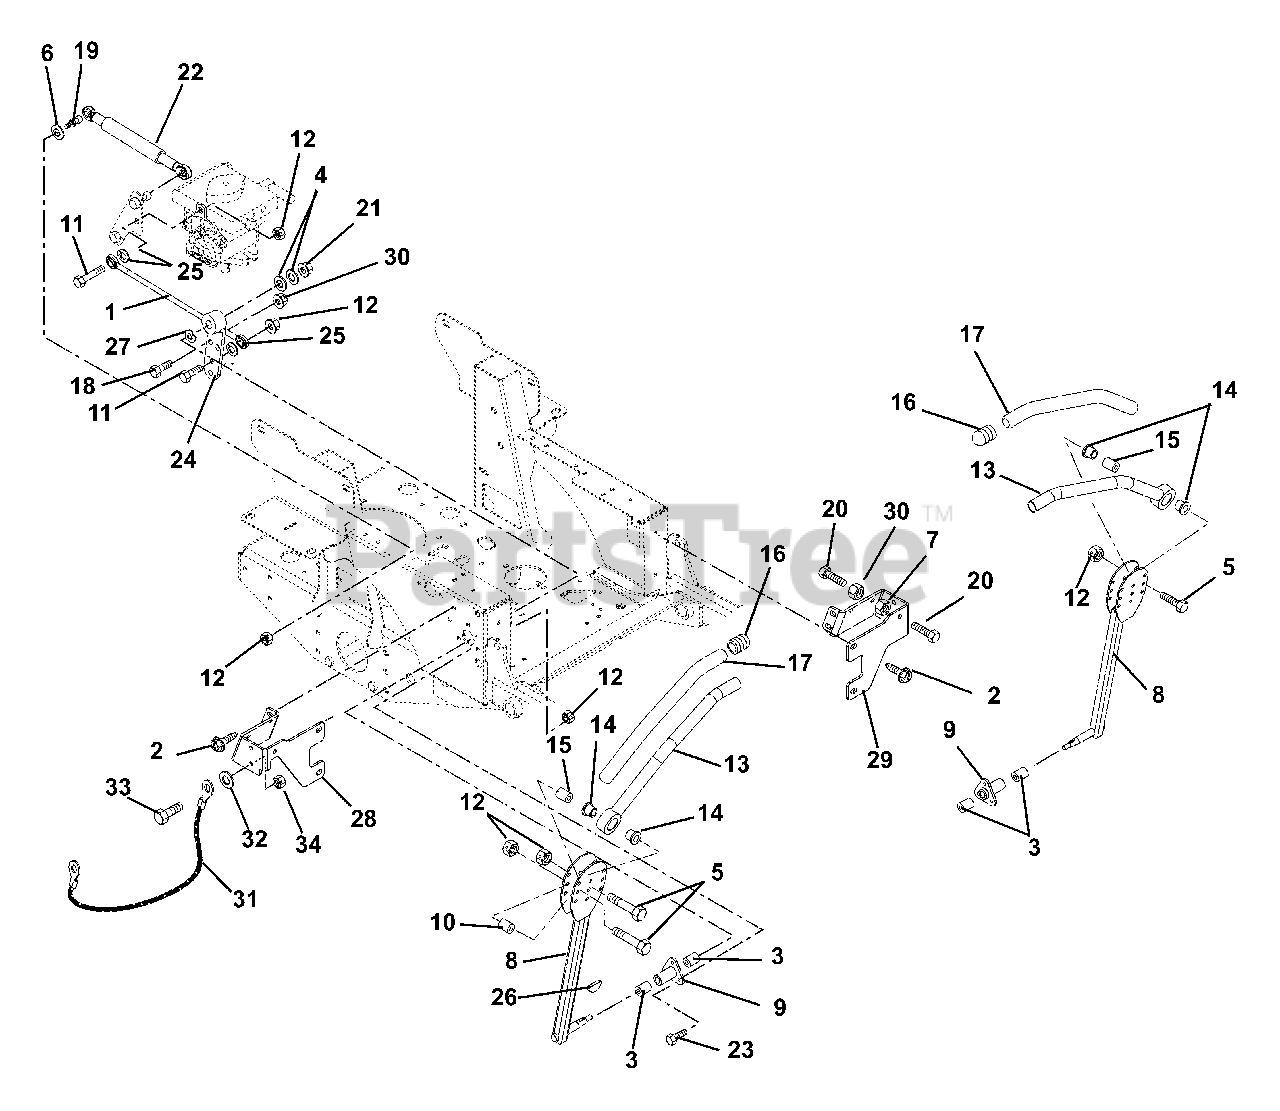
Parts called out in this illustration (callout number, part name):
1	ASSY, STEERING ROD
2	@SCR-TAP .38-16X.75 HWH TR YWZ
3	BSHG .625X.750X.500
4	@WSHR-FL-STL.406X.812X.065 YWZ
5	@BLT-HEX .31-18X1.75 GR5 YWZC
6	@WSHR-FL-STL.344X.688X.065YWZC
7	NUT-HEX-JAM .375-16 YWZC
8	CONTROL ARM - BLACK
9	BUSHING, FLANGE
10	ECCENTRIC
11	@BLT-HEX .31-18X1.25 GR5 YWZC
12	@NUT-LK-TOP-FLG .31-18 YWZC
13	HANDLE WLDMT LH
14	BSHG-FLG .762X1.48X.44 NYL
15	SPACER .328 X .76 X 1.01
16	CAPLUG - HANDLEBAR
17	GRIP - HANDLEBAR
18	BLT-HEX .375-16X1.750 FTD YWZC
19	STUD- BALL
20	@BLT-HEX .38-16X1.25 GR5 YWZC
21	@NUT-LK-TOP-FLG .38-16 YWZC
22	DAMPENER, CONTROL
23	@BLT-HEX .31-18X.75 GR5 YWZC
24	ARM, PIVOT
25	@WSHR-LK .31X.078 REG YWZC
26	KEY-WDRF .13X.63 HRD#5
27	WAVE WASHER .640X.875X.125FH
28	STOP, STEERING-RH (BLACK)
29	STOP, STEERING -LH (BLACK)
30	@NUT-LK-CTR-JAM .375-16 YWZC
31	CBL,HOOD
32	WSHR-FL-STL .265X.50X.087YWZC
33	@BLT-HEX .25-20X.75 GR5 YWZC
34	@NUT-LK-TOP-FLG .25-20 YWZC
